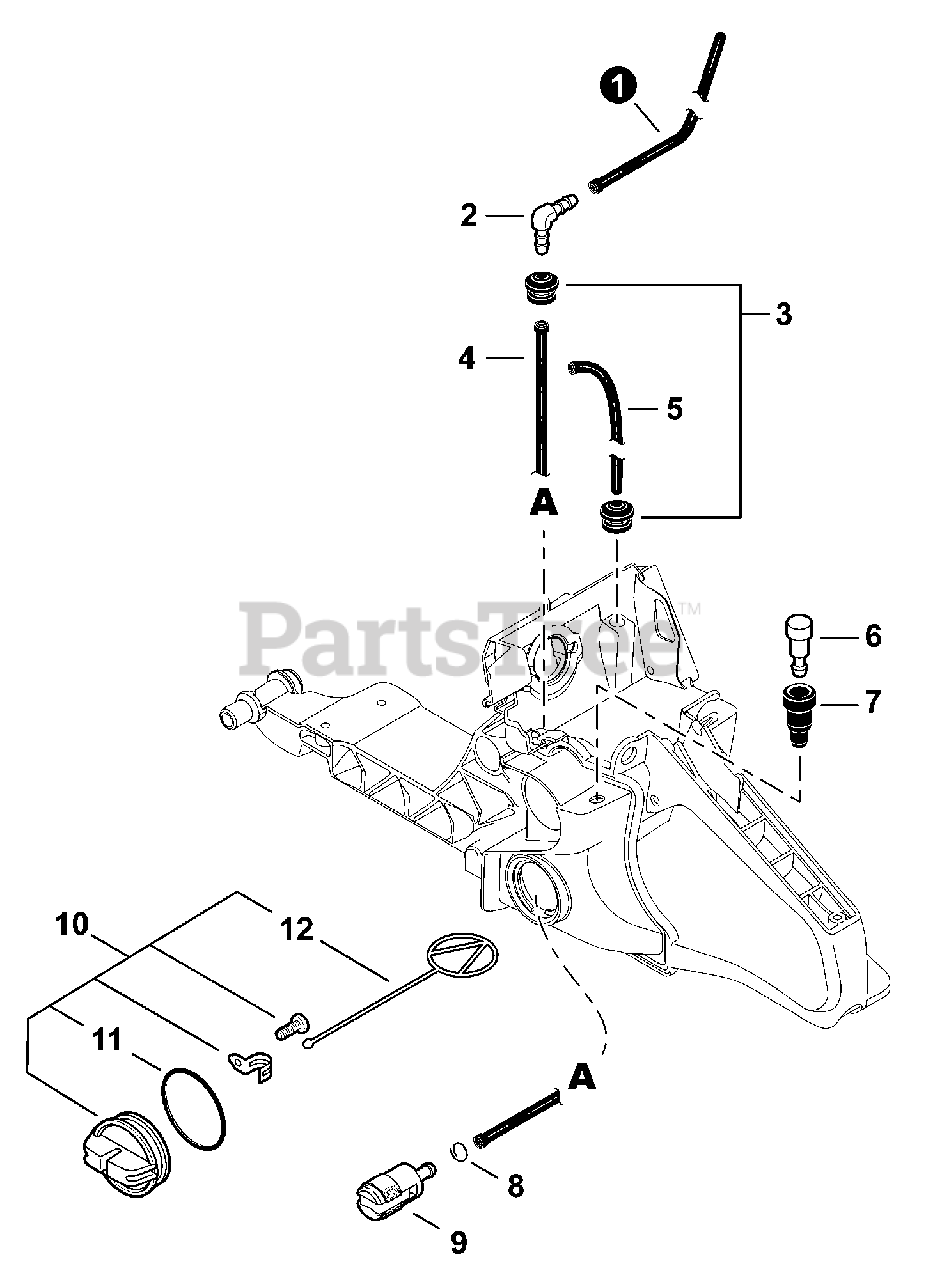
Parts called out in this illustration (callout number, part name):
1	PIPE, FUEL 3×6×135
2	CONNECTOR, PIPE Ø5.4
3	GROMMET
4	PIPE, FUEL 3×5×120 BLACK
5	PIPE, IMPULSE 3×6(8)×160
6	VENT ASSY
7	GROMMET, VENT
8	CLIP Ø6
9	FILTER, FUEL
10	CAP ASSY, FUEL
11	O-RING 29
12	CONNECTOR, CAP L= 60mm
